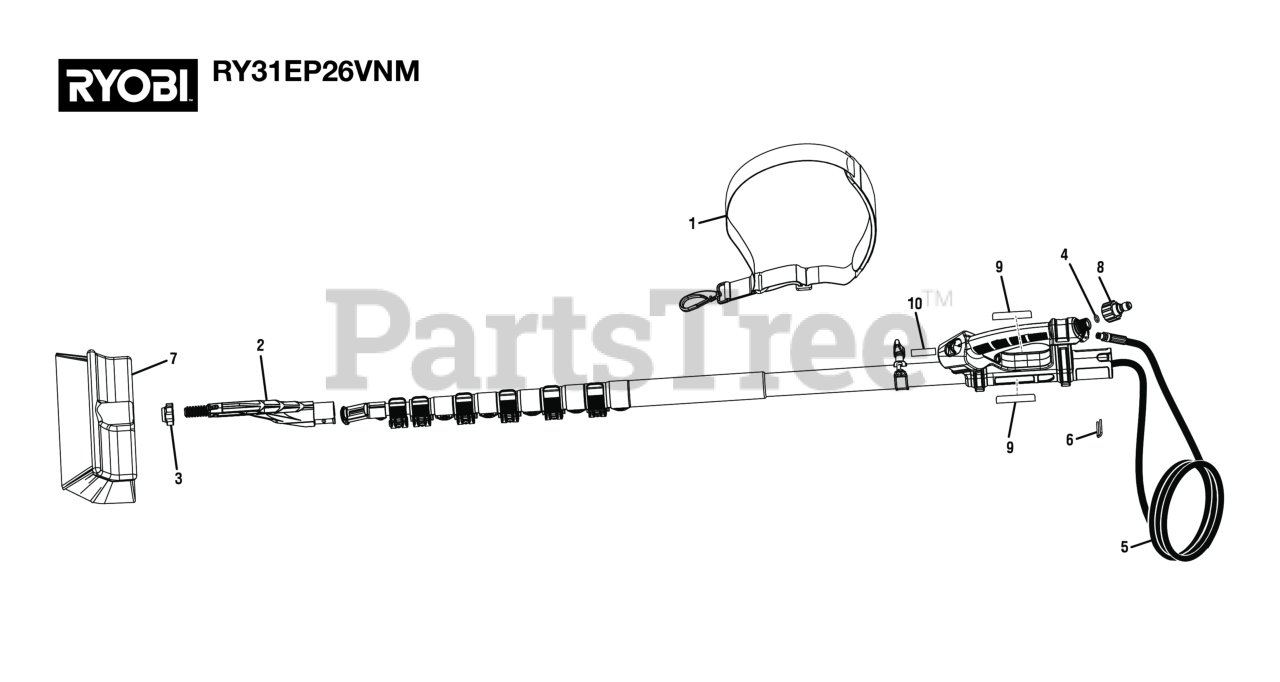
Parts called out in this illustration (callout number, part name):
1	HARNESS, RY31EP26
2	THREADED END, EXTENSION POLE
3	LOCK NUT, ACME 3/4-5, PLASTIC
4	O-RING AT QC, 9.0 x 2.5mm
5	HOSE, 19Ft, 4200PSI, 5MM, NYLON 1/4QC
7	BRUSH, BI-LEVEL
8	3/8 in. Plug (M22 Female)
9	Logo Label
10	Warning Icon Label
